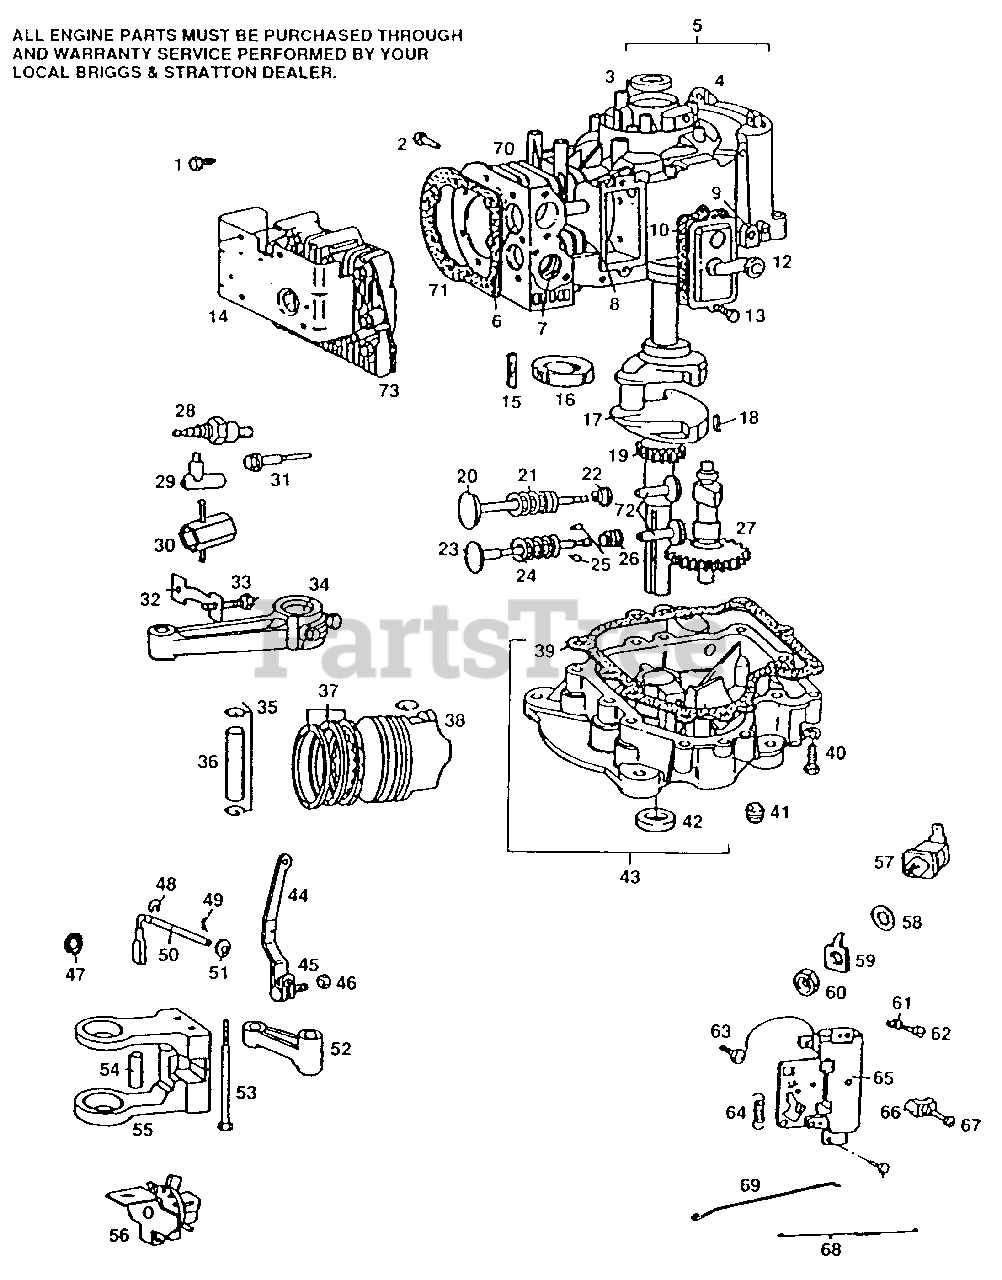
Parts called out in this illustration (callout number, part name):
1	Screw, Blower Housing Mounting Sem
2	Screw, Cylinder Shield Mtg. Sem
3	Bearing, Cylinder
4	Seal, Oil
5	Cylinder Assembly
6	Seat, Intake Valve (Standard)
7	Seat, Exhaust Valve (Standard)
8	Guide, Exhaust Valve
9	Bushing, Governor Crank (1/4" ID)
10	Gasket, Valve Cover
11	Breather Assembly
12	Tube, Breather
13	Screw, Sem
14	Cover, Cylinder Head
15	Pin, Eccentric
16	Eccentric
17	Crankshaft
18	Key, Flywheel
19	Gear, Timing
20	Valve, Intake
21	Spring, Intake Valve
22	Retainer, Intake Valve
23	Valve, Exhaust
24	Spring, Exhaust Valve
25	Retainer, Exhaust Valve Rotocoil (2)
26	Rotocoil, Exhaust Valve
27	Gear, Cam
28	Plug, Spark (1 1/2" high - 37-42mm)
29	Elbow, Spark Plug
30	Wrench, Spark Plug
31	Screw, Cylinder Head (3" long)
32	Lock, Connecting Rod Screw
33	Screw, Connecting Rod
34	Rod Assembly, Connecting
35	Lock, Piston Pin
36	Pin Assembly, Piston-Standard
36	Pin Assembly, Piston-.005 O.S.
37	Ring Set, Piston-Standard
37	Ring Set, Piston-.010" O.S.
37	Ring Set, Piston-.020" O.S.
37	Ring Set, Piston-.030" O.S.
38	Piston Assembly Standard
38	Piston Assembly-.010 O.S.
38	Piston Assembly-.020" O.S.
38	Piston Assembly-.030" O.S.
39	Gasket, Crankcase Cover (1/64" thick)
40	Screw, Base Mounting Sem
41	Plug, Oil Drain
42	Seal, Oil
43	Base, Engine
44	Lever Assembly, Governor (For 1/4" dia. Crank)
45	Bolt, Governor Lever
46	Nut, Hex 10-24
47	Seal, Oil
48	Retainer, E-Ring
49	Cotter, Hairpin
50	Crank, Governor (1/4" dia.)
51	Washer, Governor Crank (1/4" I.D.)
52	Link, Counterweight
53	Screw, Counterweight (1)
54	Pin, Counterweight (1)
55	Counterweight Assembly
56	Oil Slinger, Governor
57	Insulator Assembly
58	Washer, Lock, Shake-proof
59	Terminal, Spade
60	Nut, Hex 8-32
61	Spring, Throttle Adjustment
62	Screw, Machine Fill. Hd. 8-32 x 1/2"
63	Screw, Carburetor
64	Spring, Governor
65	Plate, Governor Control (Choke-A-Matic)
66	Clamp, Casing
67	Screw, Sem
68	Spring, Governor Link
69	Link, Governor
70	Shield, Cylinder
71	Gasket, Cylinder Head
72	Tappet Valve
73	Head, Cylinder
